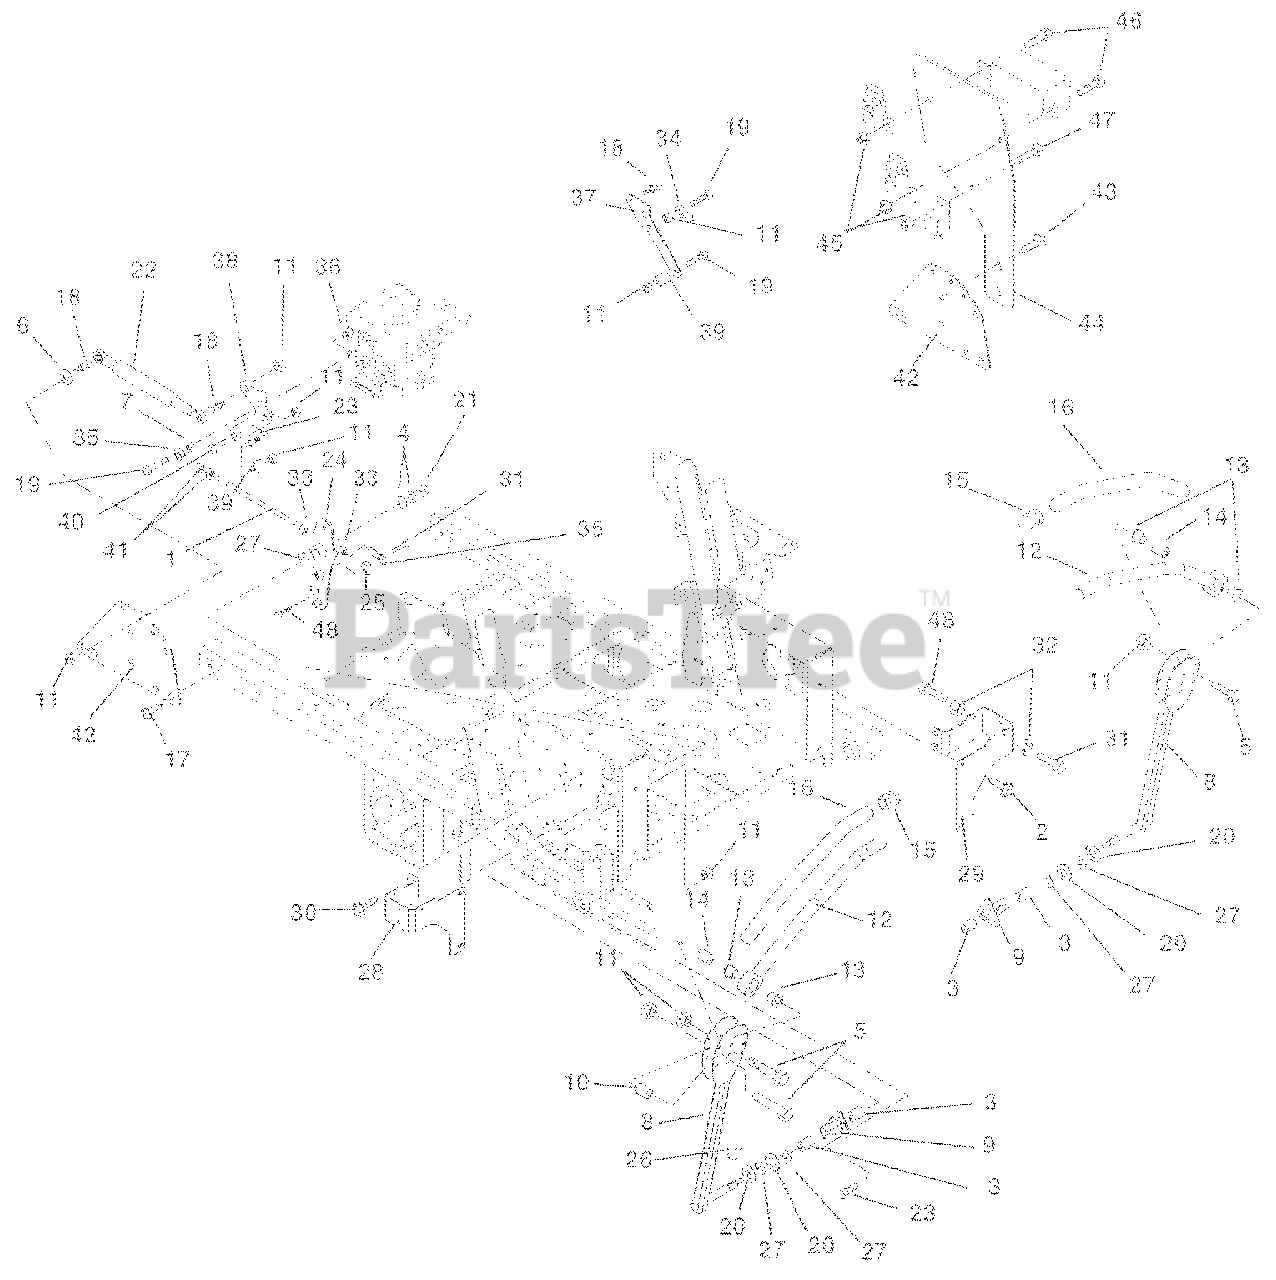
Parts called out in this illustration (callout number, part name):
1	Rod, Steering Adjustment
2	Screw, Tapping .38-16 x .75 Hex Washer Head
3	Bushing .625 x .75 x .50
4	Washer, Flat Steel .38 x .875 x .083
5	Bolt, Hex .31-18 x 1.75 Grade 5
6	Washer, Flat Steel .344 x .688 x .065
7	Nut, Hex .38-16
8	Control Arm
9	Bushing, Flange
10	Eccentric
11	Nut, Locking Top Flange .31-18
12	Handle Weldment Left-Hand
13	Bushing, Flange Nylon .762 x 1.48 x .44
15	Caplug, Handlebar
16	Grip, Handlebar
17	Screw, Tapping .31-18 x .50 Hex Washer Head
18	Stud, Ball
19	Bolt, Hex .38-16 x 1.50 Grade 5
20	Washer, Flat Steel .63 x 1.005 x .062
21	Nut, Locking Top Flange .38-16
22	Damper, Control
23	Bolt, Hex .31-18 x .75 Grade 5
24	Weldment, Pivot Arm
25	Washer, Locking .38X.094 Regular
26	Key Woodruff .13 x .63
27	Washer, Wave
28	Stop, Steering Right Hand
29	Stop, Steering Left Hand
30	Screw, Tapping .38-16 x .50 Hex Washer Head
31	Bolt, Hex .38-16 x 1.25 Grade 5
32	Nut, Hex Jam .375-16
33	Nut, Jam .375-24 Left Hand
34	Rod End .38 Right Hand
35	Rod End, .38 Left Hand
36	Nut, Locking Center .38-16
37	Bracket, Left Hand
38	Bracket, Right Hand
39	Spacer .318 x .43 x .375
40	Bolt, Hex .31-18 x .125 Grade 5
41	Nut, Jam .375-24
42	Bracket, Damper
43	Screw, Tapping .38-16 x .50 Hex Washer Head (069)
44	Bracket, EFI Box Mount (069)
45	Nut, Locking Nylon 10-24 with Insert (069)
46	Screw, Machine 10-24 x 2.00 Hex Washer Head (069)
47	Screw, Machine 10-24 x .50 Hex Washer Head (069)
48	Bolt-Hex .375-16 x 1.750 Full Thread
